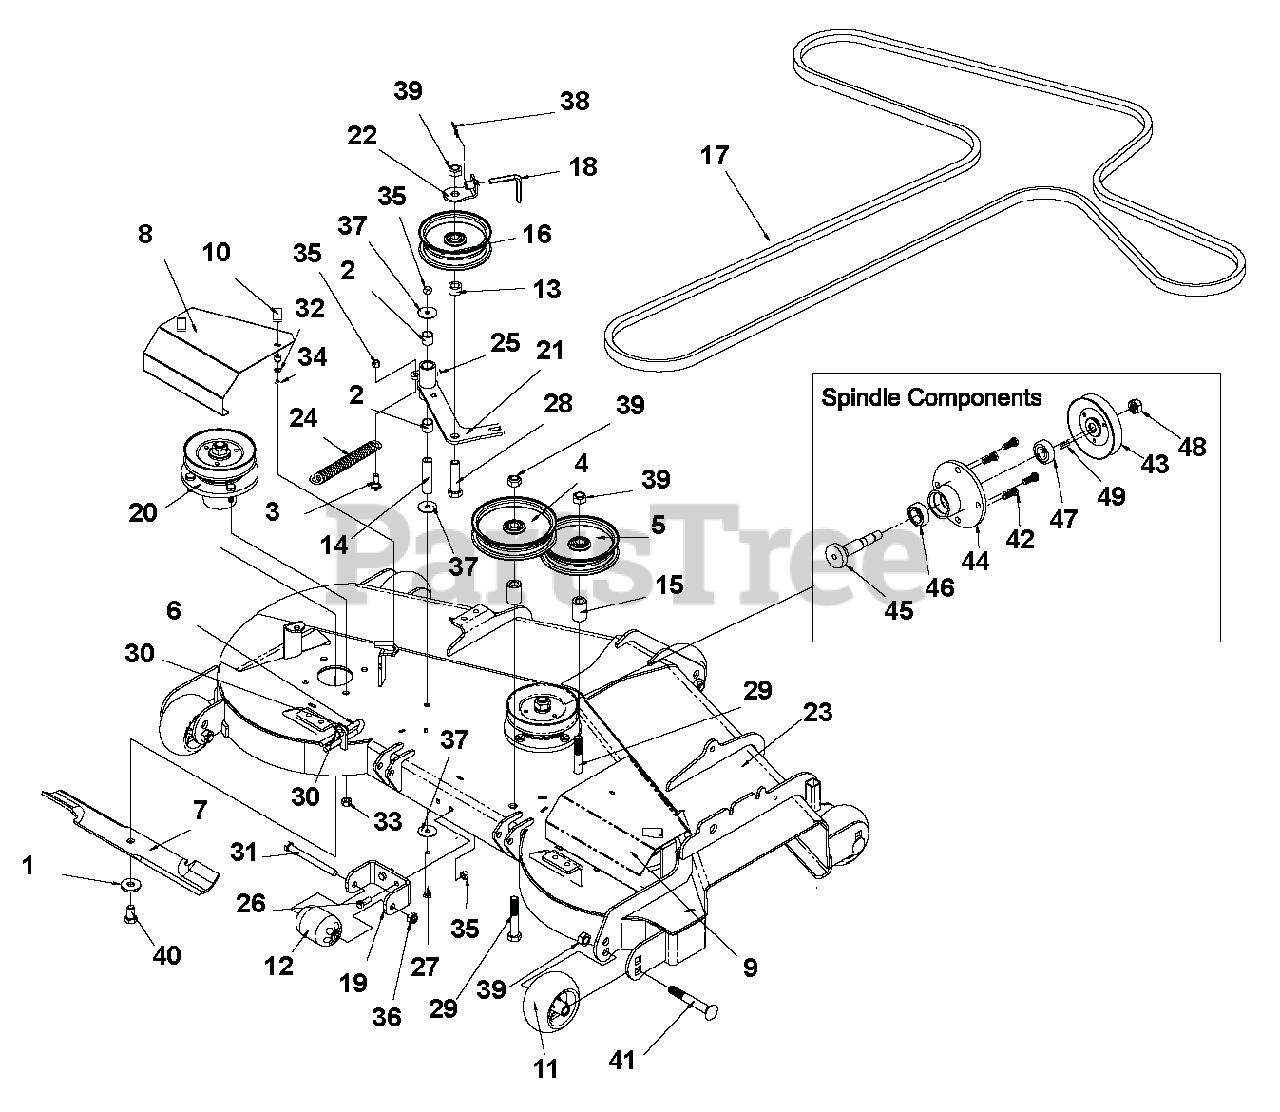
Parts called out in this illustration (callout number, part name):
1	WASHER, M14XM40XM4.5 FLAT Y
2	BRG, SLV .753X.878X.750
3	BOLT, 1/2X1.06X3/8-16 SLD 5 Y
4	PULLEY, FLAT 6.00X.635 W/BRG
5	PULLEY, FLAT 5.50X.635 W/BRG
6	U-BOLT, RD .63X4.50X3/8-16SP Y
7	BLADE, 18.000 X 1.00 LIFT
7	BLADE, 16.500 X 1.00 LIFT
8	SHIELD, LH ZTM BELT (ARIENS)
9	SHIELD, RH ZTM BELT (ARIENS)
10	LATCH, 12-24 SOUTHCO
11	WHEEL, GAUGE 5.00 X 3.31
12	WHEEL, GAUGE 2.56 X 3.94 SYM
13	BUSHING, .688 X 1.13 X .625
14	TUBE, RD .750 X .156 X 3.05
15	BUSHING, .688IDX 1.13 X 1.68L
16	PULLEY, FLAT 5.00X.635 W/BRG
17	BELT, HB 148.0 OC AMD OHR
17	BELT, HB 140.9 EL AMD
18	BELT KEEPER, 90? W/HOLE
19	BRACKET, ANTI-SCALP
20	ASSY, SPINDLE BALL BRG
21	WLDT, DECK BELT TENSIONER
22	WLDT, BELT KEEPER Y
23	52 ARIENS ZOOM DECK W/DCALS
23	48 ARIENS ZOOM DECK W/DCALS
24	SPRING, EXT .910X.177X6.15 Y
25	FTG, 1/4-28 TPR 45 GREASE ZERK
26	@BLT-HEX .38-16X1.00 GR5 YWZC
27	BOLT, 3/8-16X4.00 HEX 5 Y
28	BOLT, 5/8-11X2.75 HEX 5 Y
29	BOLT, 5/8-11X3.50 HEX 5 Y
30	@NUT-HEX .31-18 YWZC
31	BOLT, M12X1.75X130 HEX 8.8 Y
32	WASHER, M6 REG FLAT Y
33	NUT, 7/16-20 HEX GR5 Y
34	LOCKNUT, 12-24 NYLOC Y
35	NUT, .38-16 LOW CROWN LK ACORN
36	LOCKNUT, M12X1.75 NYLOC Y
37	WASHER, .375X1.50X.063 FLAT Y
38	RING, RUE .625 X .072 X 1.690
39	LOCKNUT, 5/8-11 CROWN Y
40	BOLT, 9/16-12X1.00 HEX 8 Y
41	BOLT, 5/8-11X4.50 CRG Y
42	BOLT, 7/16-20X1.22 SPC 5 Y
43	PULLEY, V-BELT 5.75X.750 W/KEY
43	PULLEY, V-BELT 5.38X.750 W/KEY
44	SPINDLE, MACHINED BALL BRG
45	SHAFT, BLADE SPINDLE
46	BRG, BAL .984X2.05X.591 - 6205
47	BRG, BAL .787X2.05X.591
48	LOCKNUT, 3/4-16 CROWN PL
49	KEY, .250 X .250 X 1.00 SQ
